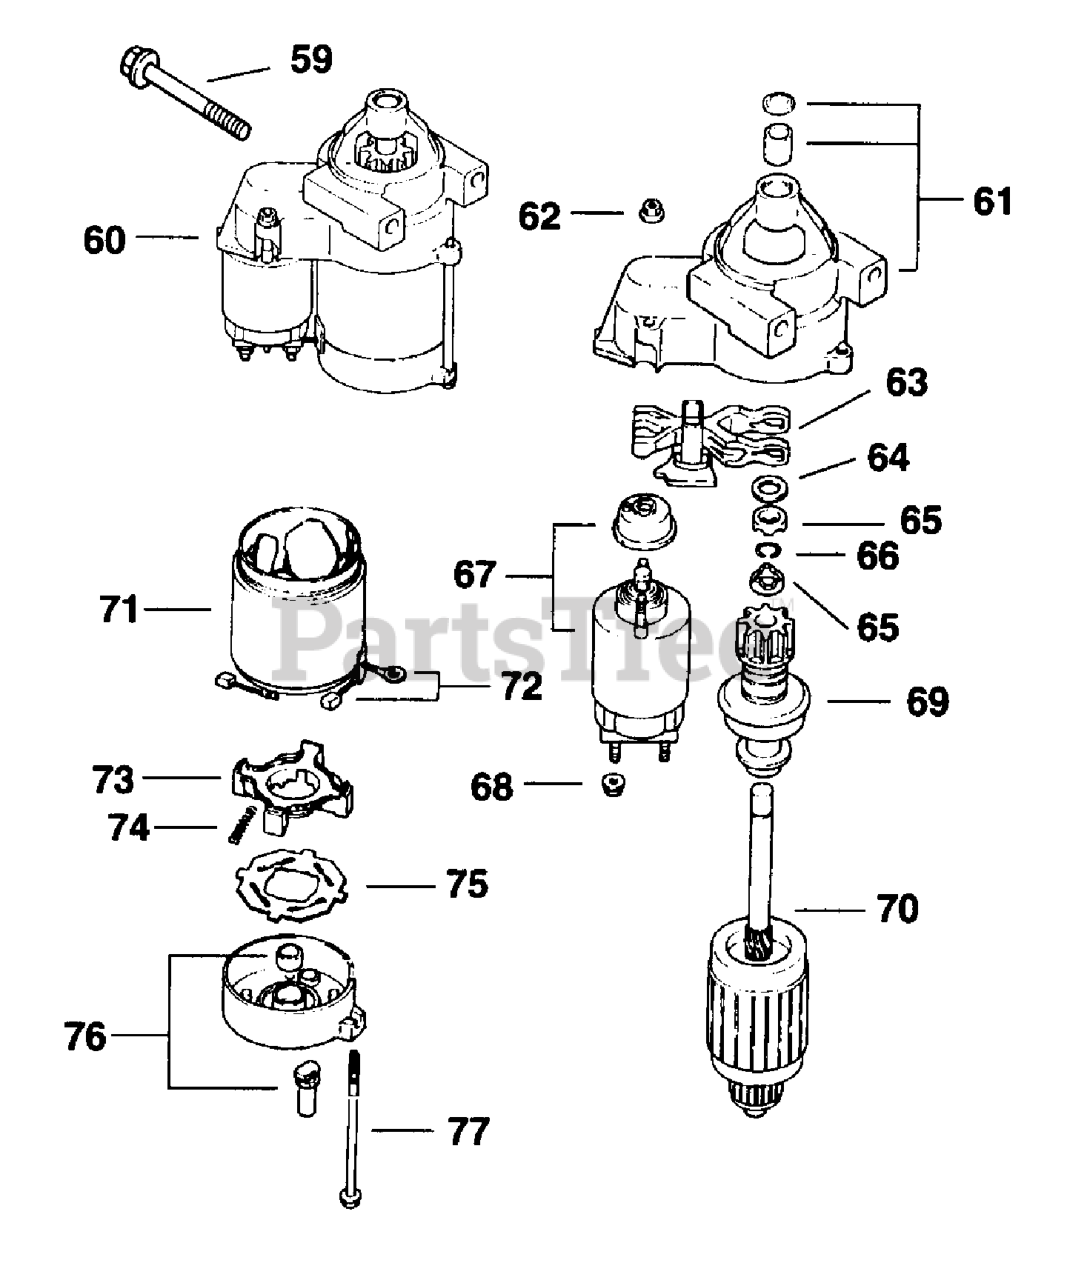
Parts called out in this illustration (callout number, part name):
59	Screw, hex. flange M8x1.25x80.6
61	DRIVE END CAP
63	LEVER, DRIVE
64	KIT - USE 24 755 84
65	KIT - USE 24 755 84
66	KIT - USE 24 755 84
69	DRIVE PINION
70	ARMATURE - DISCONTINUED
71	FRAME W/BRUSHES - DISCONTINUED
72	BRUSH & SPRING KIT
73	BRUSH HOLDER
74	SPRING, BRUSH
75	INSULATOR
76	COMMUTATOR END CAP - DISCONTINUED
77	THRU BOLT
